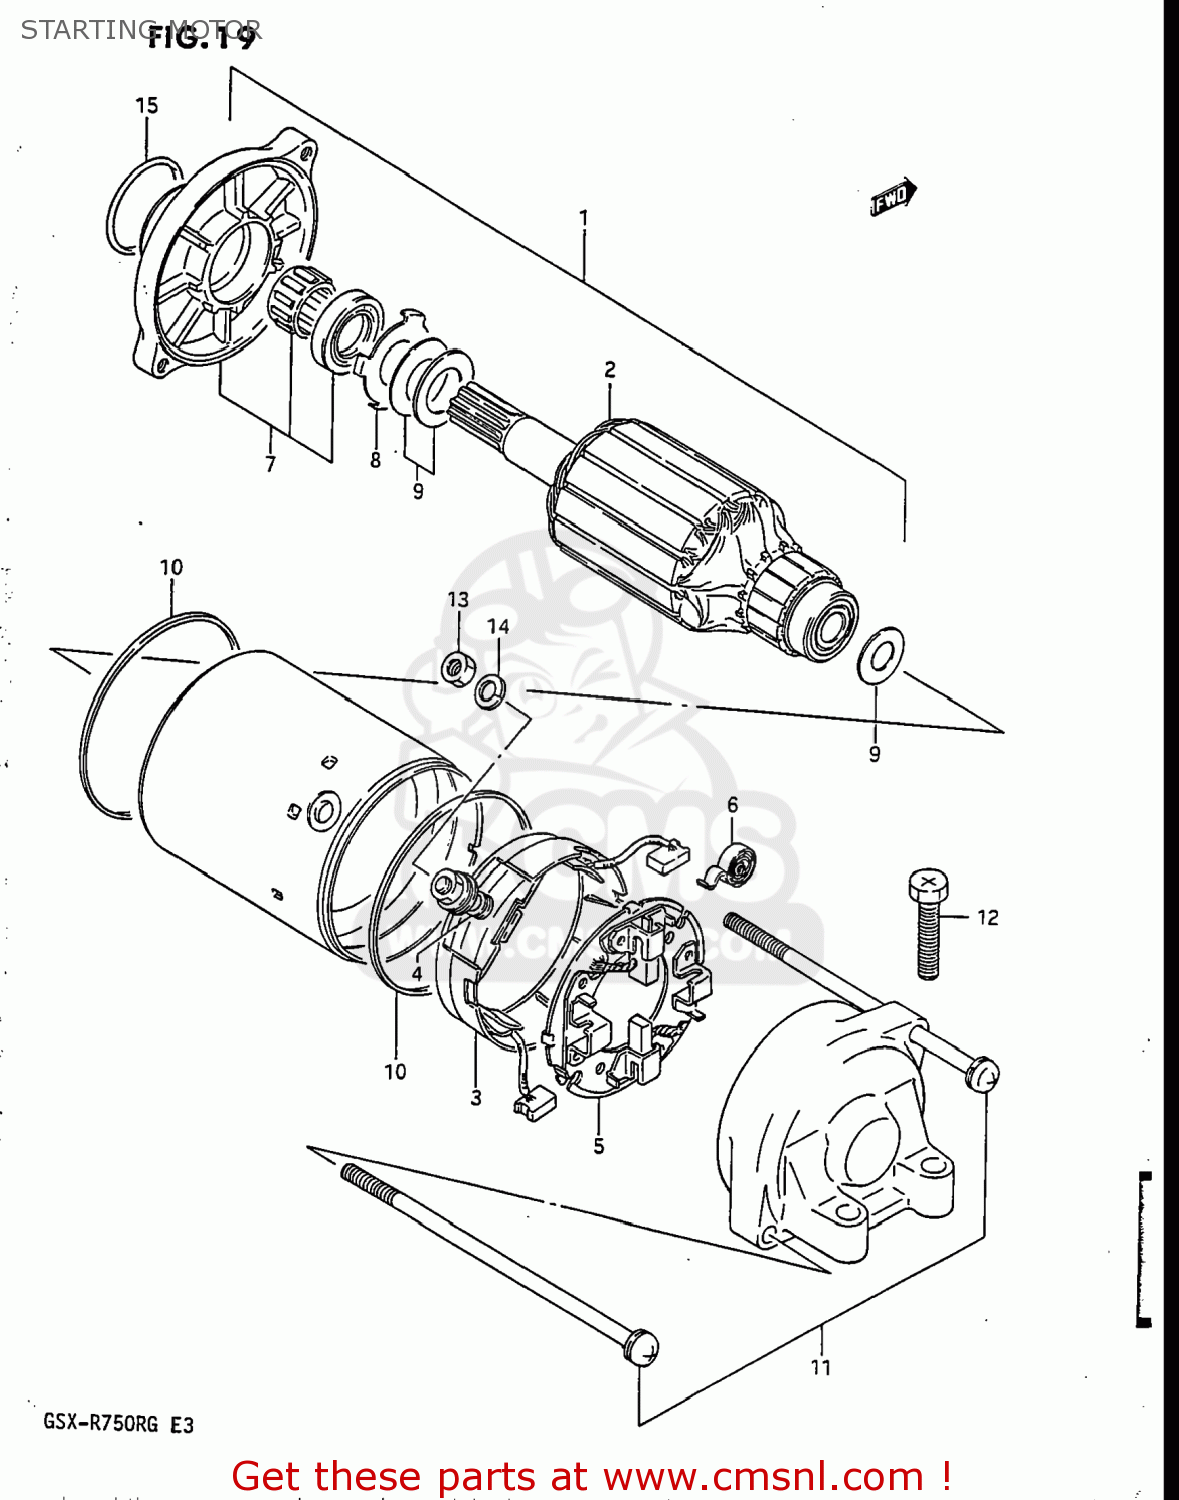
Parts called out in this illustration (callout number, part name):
1	MOTOR ASSY,STARTING
2	ARMATURE
3	TERMINAL SET,BRUSH,PLUS
4	O RING
5	HOLDER SET,BRUSH(-)
6	SPRING,BRUSH
7	BRACKET SET,STARTING MOTOR
8	SHIM SET
9	SHIM SET
10	SEAL,RING
11	BOLT
12	SCREW (6X25)
13	NUT
14	WASHER,LOCK
15	O RING(D:3,ID:24.5)
